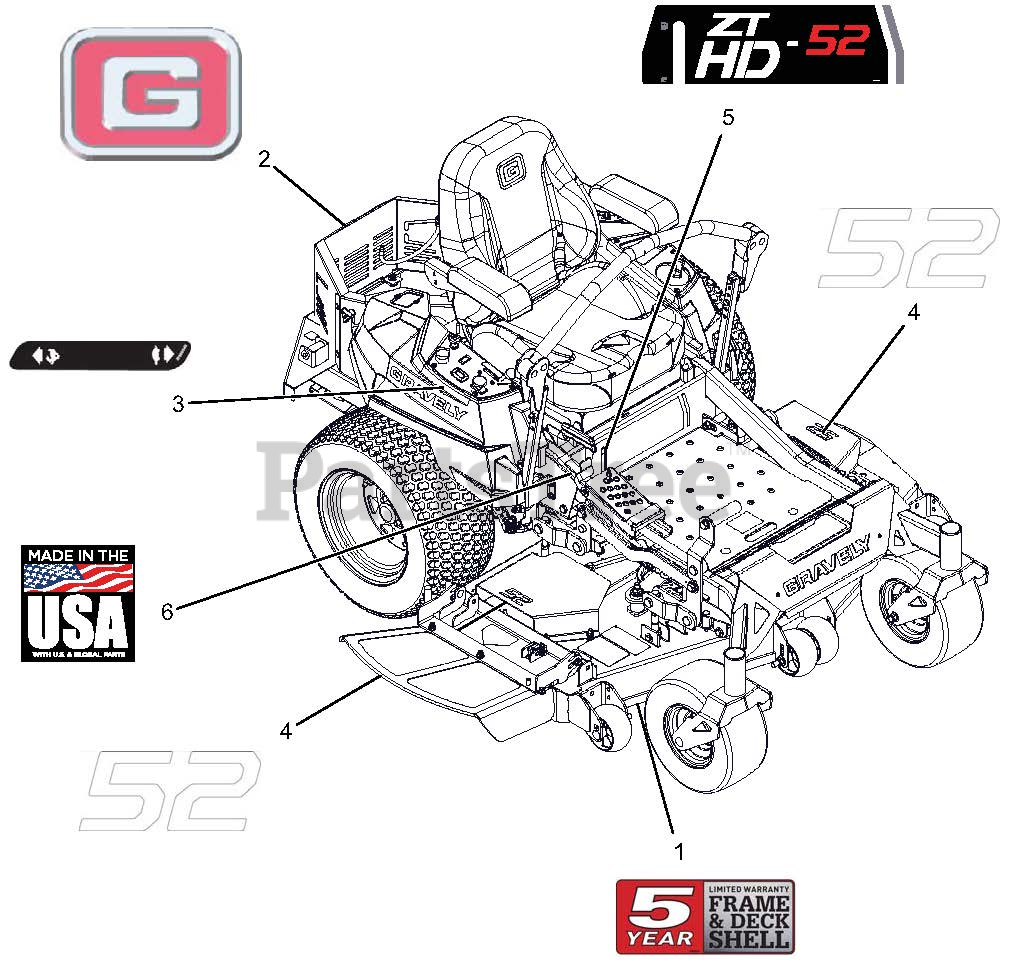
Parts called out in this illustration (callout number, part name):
1	DECAL,DECK WARRANTY-FAB GRVLY
2	DECAL, GRAVELY BRAND
3	DECAL, DASH DECAL
4	DECAL, 52"
5	DECAL - 52HD
6	DECAL, MADE IN USA
